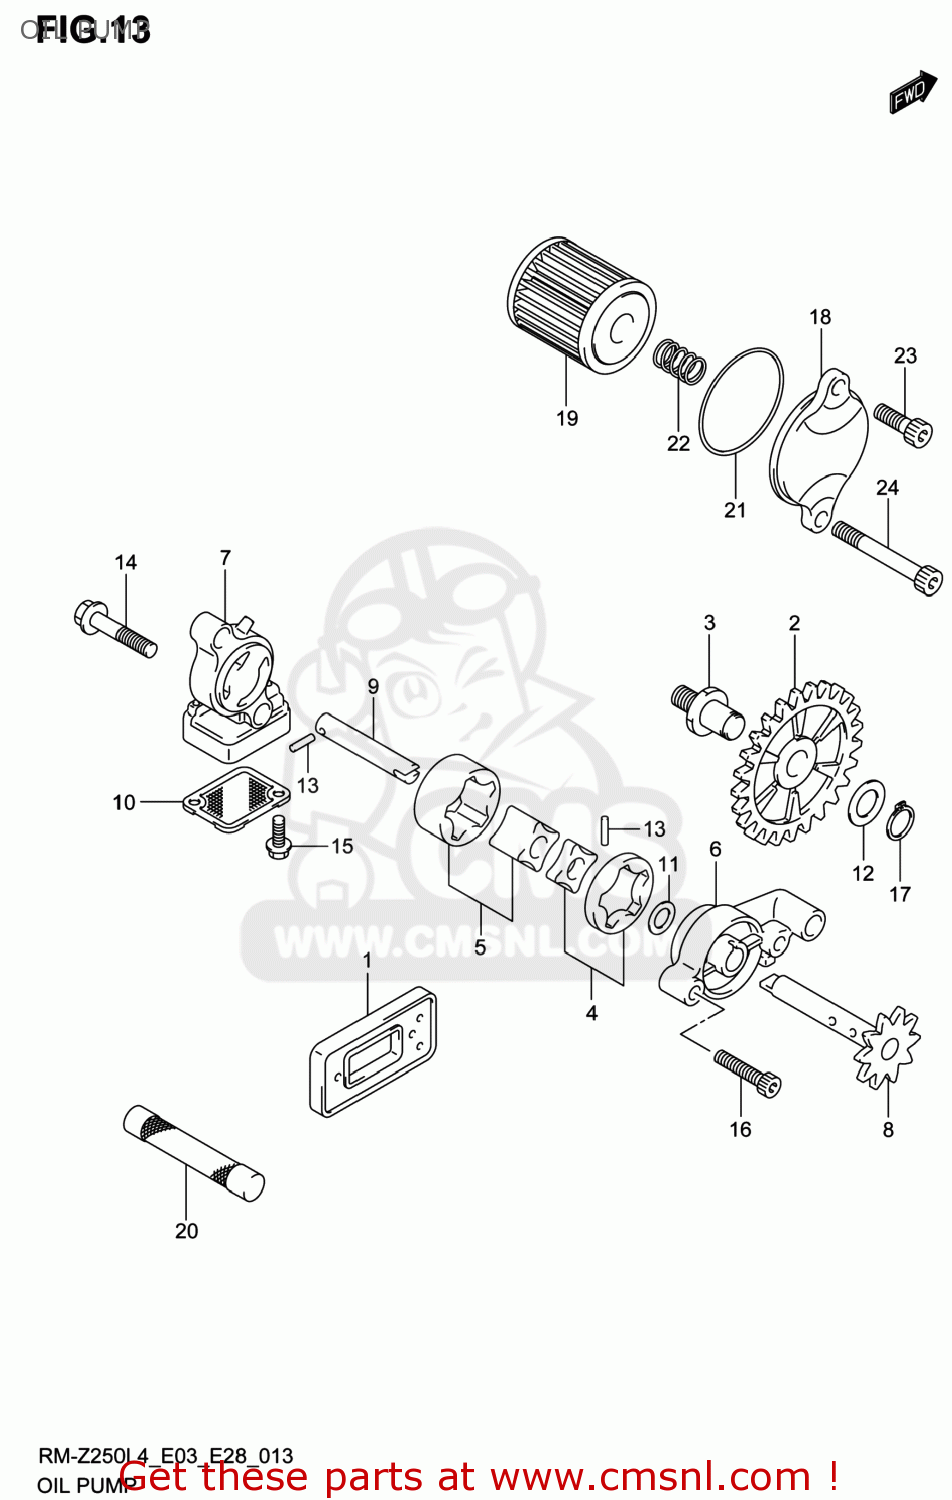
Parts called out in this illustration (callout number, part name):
1	VALVE ASSY,OIL REED
2	GEAR,OIL PUMP IDLE
3	SHAFT,OIL PUMP IDLE GEAR
4	ROTOR SET,OIL PUMP NO.1
5	ROTOR SET,OIL PUMP
6	COVER,OIL PUMP NO.1
7	COVER,OIL PUMP NO.2
8	SHAFT,OIL PUMP DRIVEN GEAR
9	SHAFT,OIL PUMP NO.2
10	STRAINER,OIL PUMP NO.2
11	SHIM(8X12X0.8)
12	SHIM(10X18X0.5)
13	PIN(2.5X11.8)
14	BOLT
15	BOLT
16	BOLT
17	CIRCLIP
18	CAP,ENG OIL FILTER OUTER
19	FILTER ASSY,ENGINE OIL
20	STRAINER,ENGINE OIL
21	O RING(D:2,ID:38.5)
22	SPRING
23	BOLT
24	BOLT
